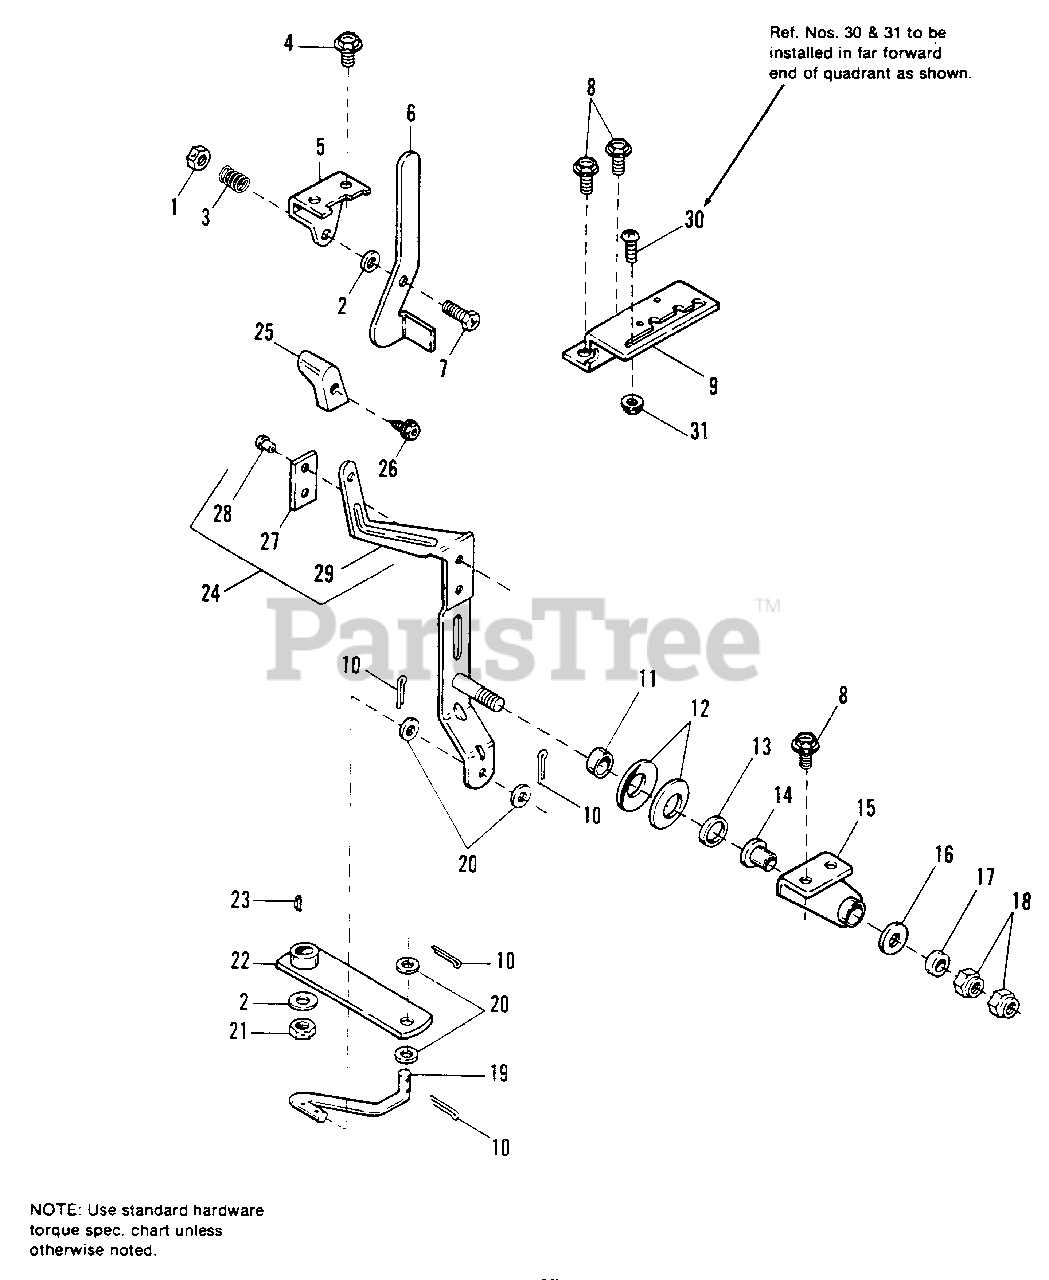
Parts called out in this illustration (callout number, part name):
1	LOCKNUT, Hex, 5/16-18
2	WASHER, Plain, 5/16
3	SPRING, Compression
4	SCREW, Taptite, 1/4-20 x 1/2
5	SUPPORT, Handle, Neutral
6	HANDLE, Neutral
7	CAPSCREW, Hex, 5/16-18 x 1-3/4
8	SCREW, Taptite, 5/16-18 x 3/4
10	PIN, Cotter
12	WASHER, Spring
13	WASHER, Special
15	SUPPORT ASSY., Control
18	LOCKNUT, Hex, 5/8-11
19	ROD, Control
20	WASHER, Plain, 13/32 x 1
21	LOCKNUT, Hex, Jam, 3/8-16
22	ARM ASSY., Control
23	KEY, Woodruff, #3, 1/8 x 1/2
24	CONTROL ASSY., (Incl. Ref. Nos. 27, 28 & 29)
26	SCREW, Plastite, 1/4-20 x 1
27	PLATE, Wear
28	RIVET, Tubular, 3/16 x 5/16
30	SCREW, Truss Hd., 1/4-20 x 3/4 (1691340 only)
31	NUT, Hex Flange Lock, 1/4-20 (1691340 only)
